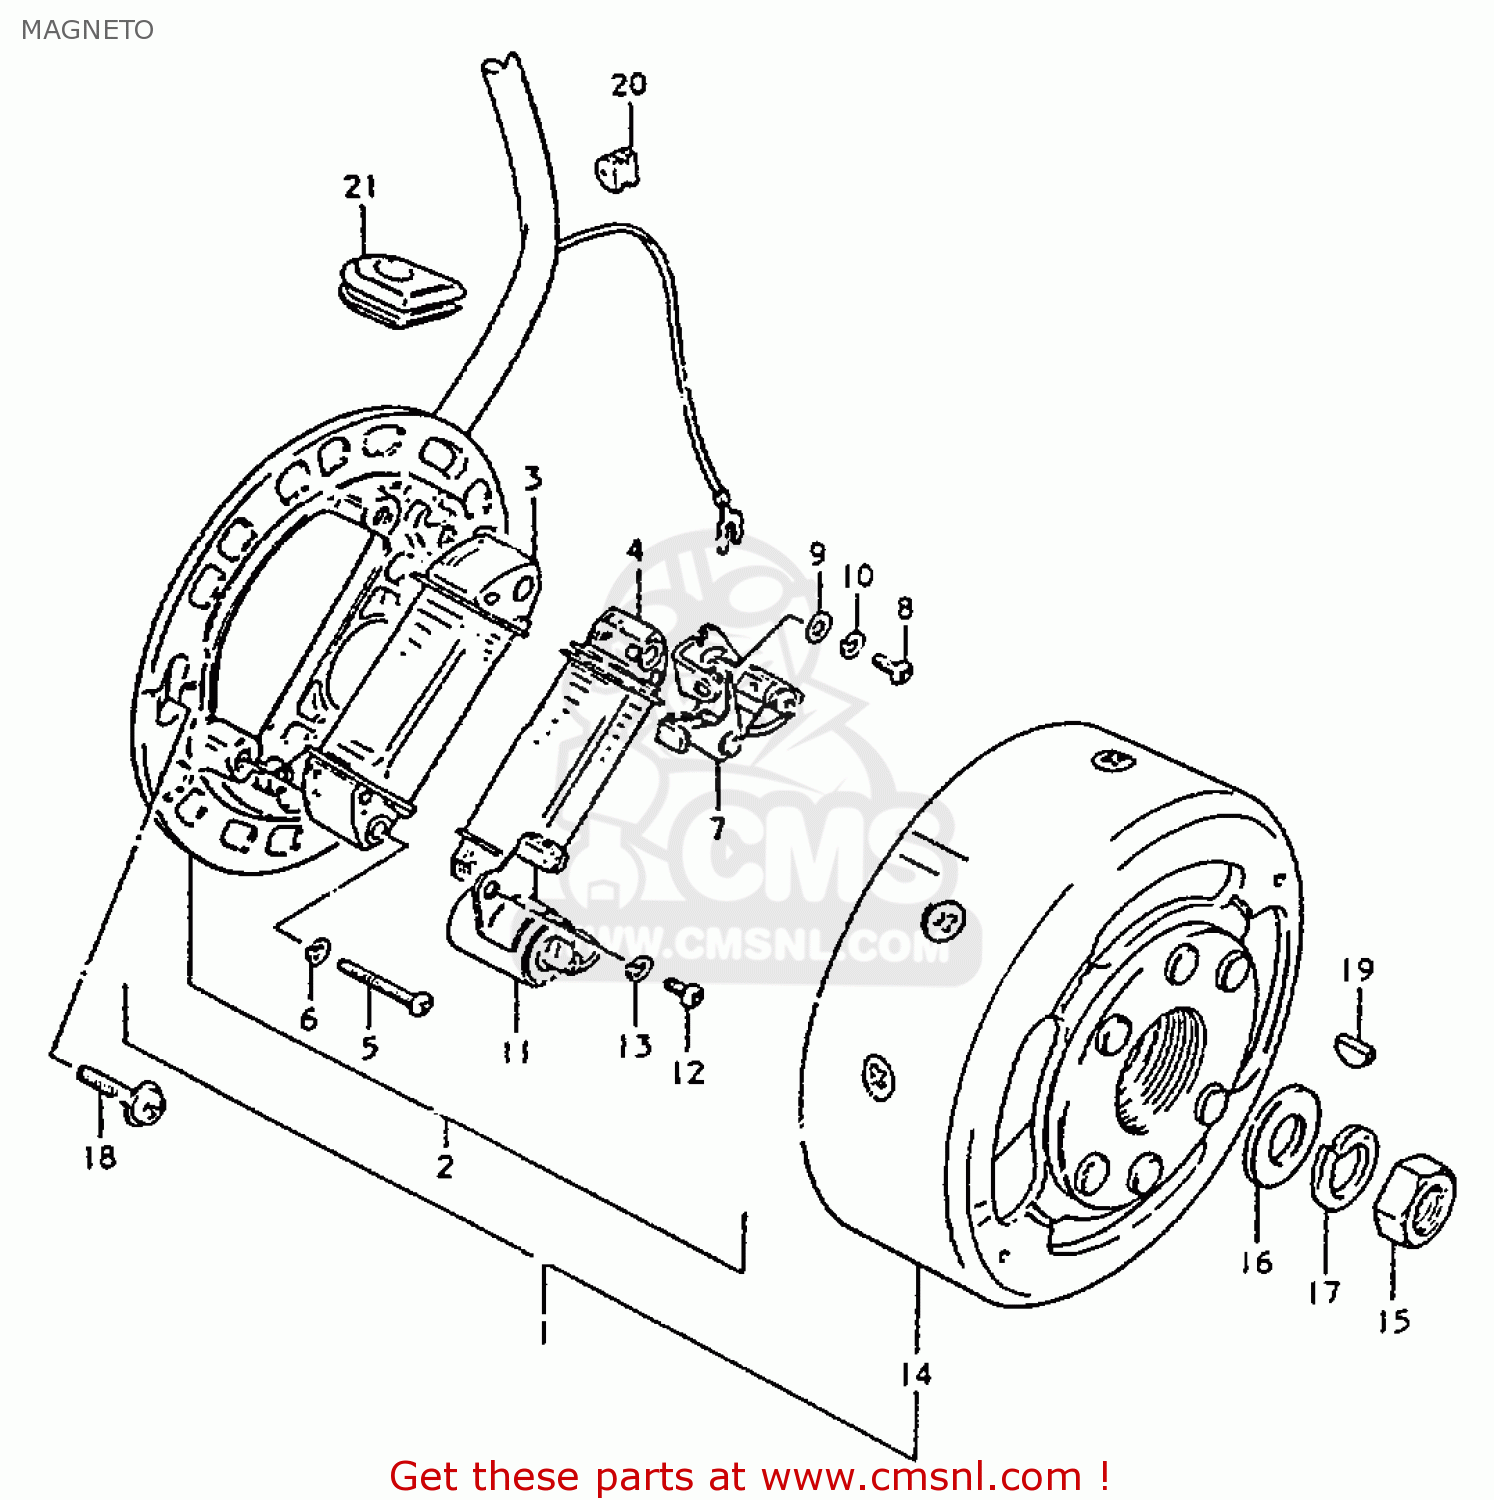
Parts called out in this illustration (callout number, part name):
1	MAGNETO ASSY
2	STATOR ASSY
3	COIL, LIGHTING
4	COIL,PRIMARY
5	SCREW (4X30)
6	LOCK WASHER
7	POINT ASSY,CONTACT
8	SCREW(4X10)
9	WASHER
10	LOCK WASHER
11	CONDENSER
12	SCREW
13	LOCK WASHER
14	ROTOR ASSY
15	NUT (10MM)
16	WASHER
17	LOCK WASHER
18	SCREW(5X14)
19	KEY
20	GROMMET,NEUTRAL LEAD WIRE
21	GROMMET
